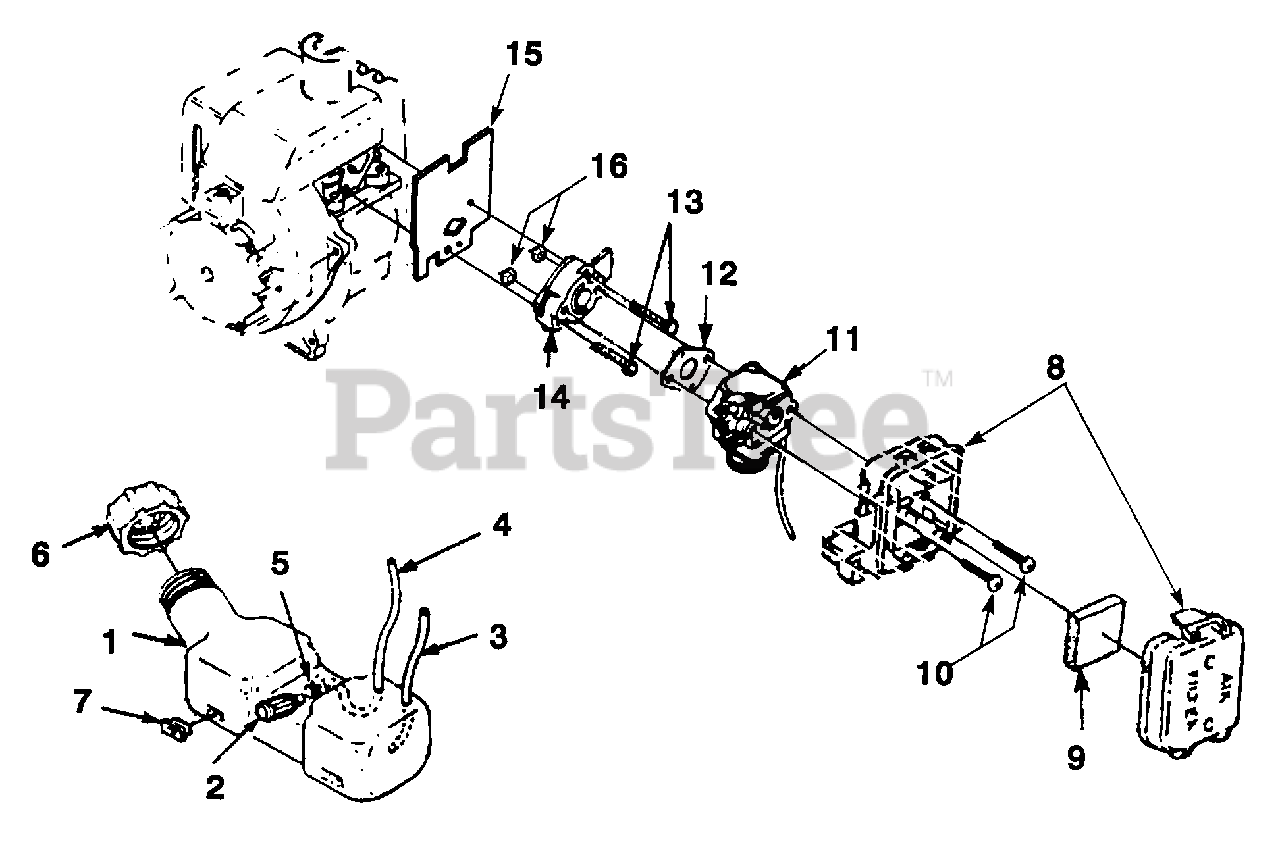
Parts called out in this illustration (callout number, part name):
1	Fuel Tank
2	Filter-Fuel
3	Tubing-Rubber (8")
4	Tubing-Rubber (8")
5	Clamp-Wire
6	Fuel Cap
7	Bumper-Rubber
8	Air Filter Kit
9	Air Filter
10	Screw-Sems Hex Hd (10-24 x 2 1/2")
11	Carburetor
12	Gasket, Carburetor
13	Screw, Sems (10-24 x 1")
14	Heat Dam
15	Heat Dam Gasket
16	Nut-Hex (10-24)
